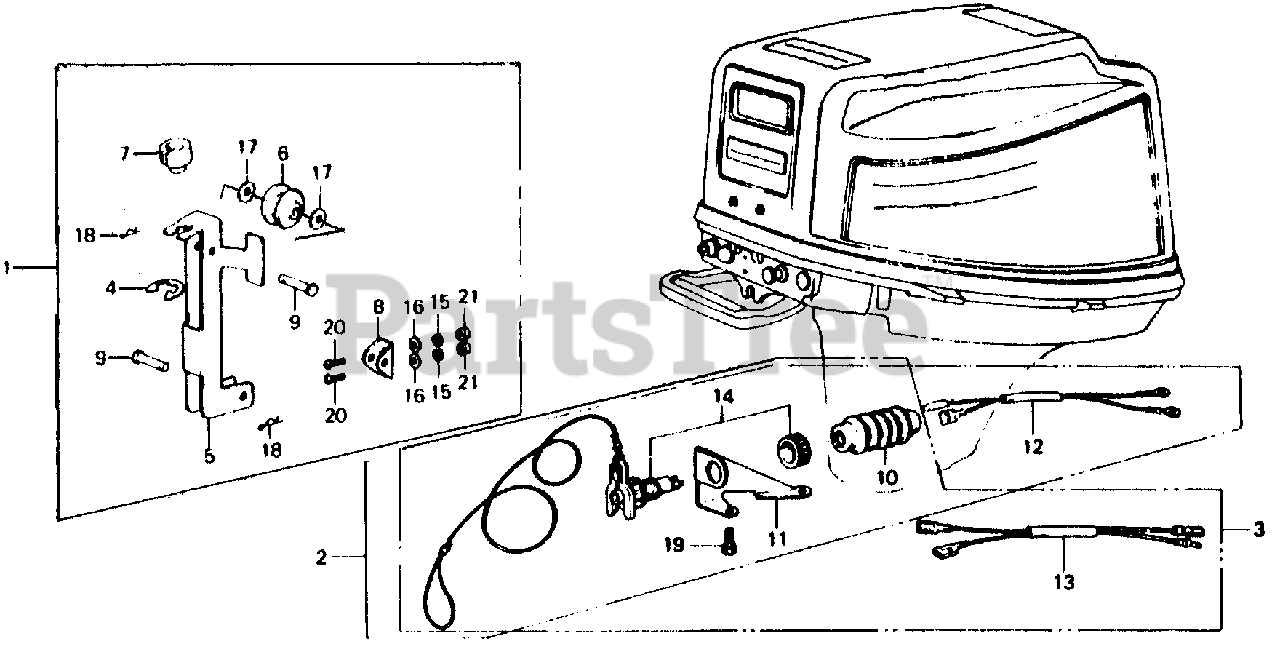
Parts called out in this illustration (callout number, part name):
1	STARTER KIT, VERTICAL (N/A: SEE COMPONENTS)
2	SWITCH KIT, SAFETY
5	STAY, VERTICAL STARTER
6	IDLER, VERTICAL STARTER
7	GUIDE, ROPE
8	BRACKET, VERTICAL STARTER
9	PIN, VERTICAL STARTER
10	RUBBER, SEALING (NOT AVAILABLE)
11	STAY, SAFETY SWITCH (NOT AVAILABLE)
12	WIRE B, SWITCH (NOT AVAILABLE)
14	SWITCH, SAFETY
15	WASHER, SPRING (6MM)
16	WASHER, PLAIN (6MM)
17	WASHER (10MM)
18	PIN, LOCK (10MM)
19	BOLT, HEX. (6X12)
20	SCREW, PAN (6X12)
21	NUT, HEX. (6MM)
